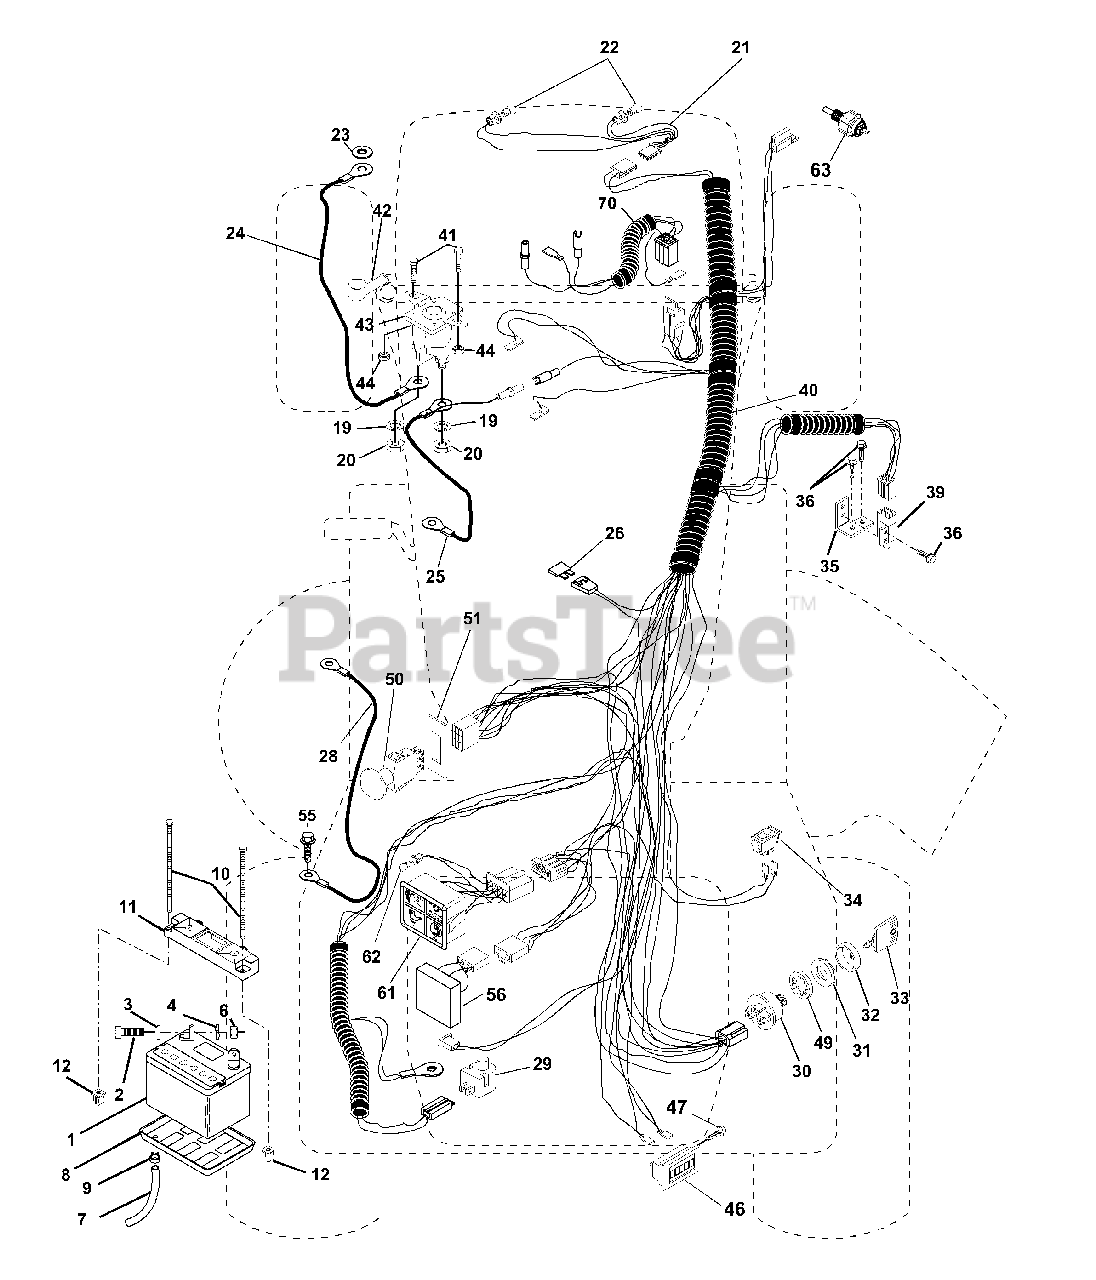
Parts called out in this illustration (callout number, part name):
1	Battery
2	Bolt, Hex Head 1/4-20 x 3/4
3	Washer 9/32 x 5/8 x 16 Gauge
4	Washer, Lock 1/4
6	Nut, Hex 1/4-20
7	Tube, Tray, Battery
8	Tray, Battery
9	Clamp, Hose
10	Bolt, BTR FRT 1/4-20 x 7-1/2 Zinc
11	Holddown Battery Dash Mount
12	Nut, Push Nylon Battery FRT 1/4"
19	Washer, Lock 1/4
20	Nut, Hex, Jam 1/4-20
21	Harness, Socket, Light w/4152J
22	Bulb, Light
24	Cable, Battery
25	Cable, Starter, 6 Ga W/16 Wire 22" Red
28	Cable, Battery
29	Switch, Plunger
30	Switch, Ignition
31	Nut, Ignition
32	Cover, Switch, Ignition
33	Key, Molded
34	Switch, Light
35	Bracket Switch Interlock
36	Screw, Hex Tap #10-24 UNC
39	Switch, Interlock (4 Terminal)
40	Harness, Ignition
41	Bolt Blk Fin Hex 1/4-20 Unc x 1/2
42	Cover, Terminal
43	Solenoid
44	Nut Keps Blk Hex 1/4-20 Unc
46	Meter, Hour
47	Screw #10-24 x 1/2
49	Washer Lock Internal Tooth 5/8
50	Switch, P.T.O.
51	Ring, Retainer, Pto
55	Screw Thdrol 5/16-18 x 1/2 TYT
56	Sensor, Low Voltage
61	Package, Light
62	Bulb, Light Package
63	Switch, Engine Oil Pressure
70	Harness, Engine
